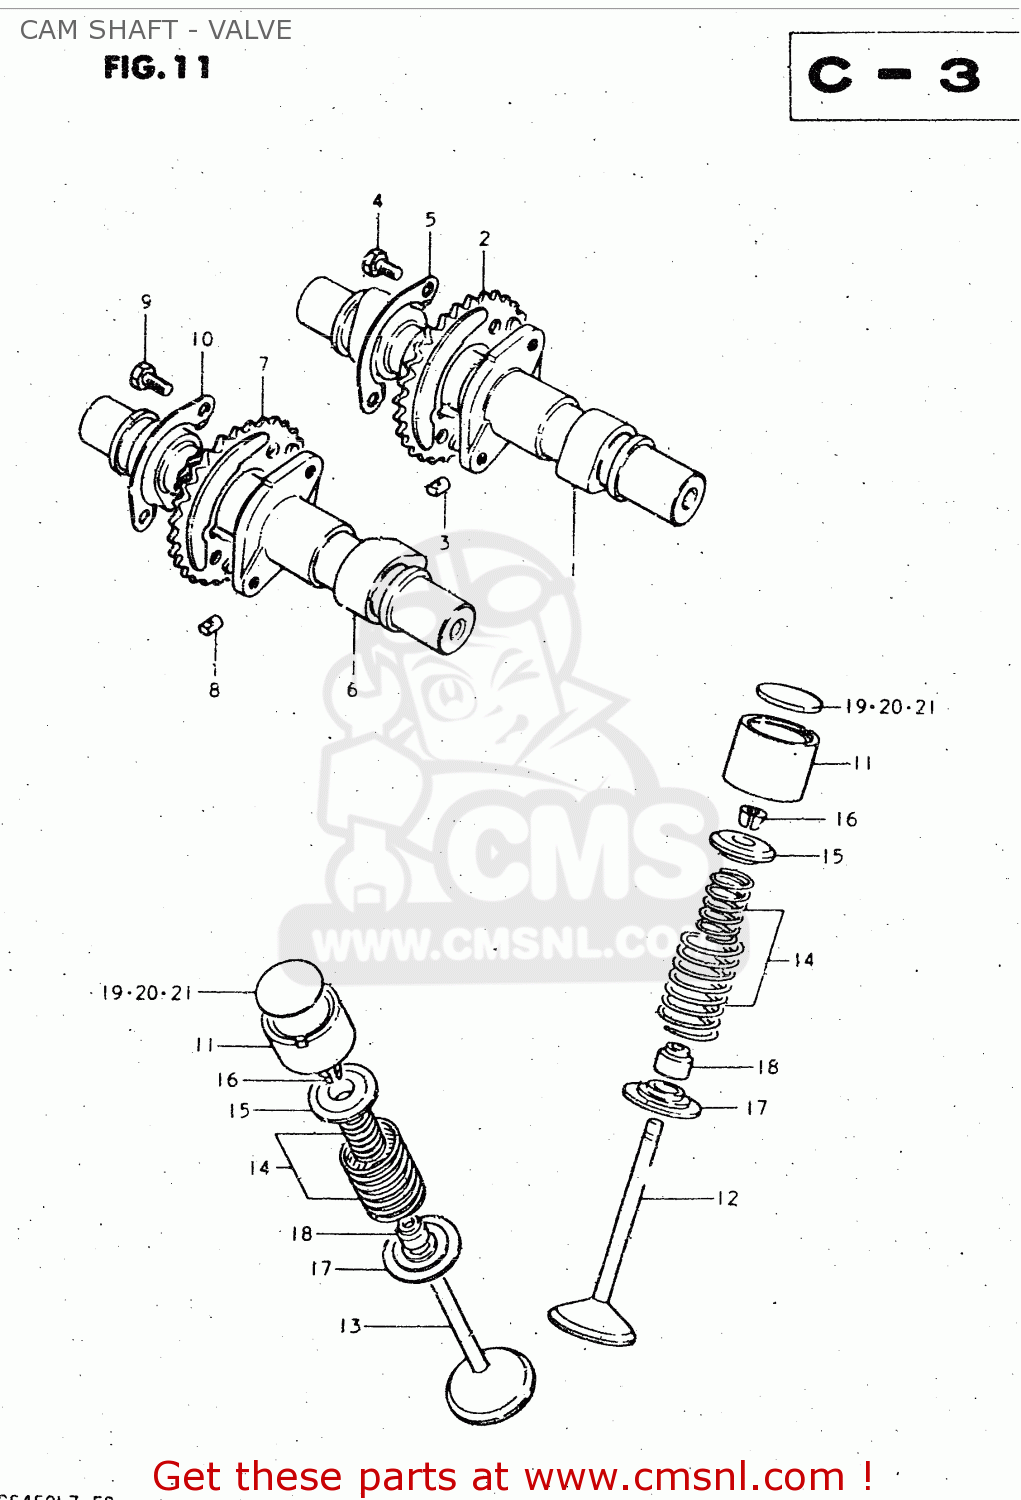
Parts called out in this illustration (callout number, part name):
1	CAMSHAFT,INTAKE
2	SPROCKET (NT:30)
3	PIN,SPROCKET
4	BOLT(6X12.5)
5	WASHER,CAM CHAIN SPROCKET
6	CAMSHAFT,EXHAUST
7	SPROCKET (NT:30)
8	PIN,SPROCKET
9	BOLT(6X12.5)
10	WASHER,CAM CHAIN SPROCKET
11	TAPPET
12	VALVE,INTAKE
13	VALVE,EXHAUST
14	SHIM,TAPPET
15	RETAINER,VALVE SPRING
16	COTTER VALVE
17	SEAT,VALVE SPRING
18	SEAL,OIL(7X14.4X9)
19	SHIM,TAPPET
20	SHIM,TAPPET
21	SHIM,TAPPET
